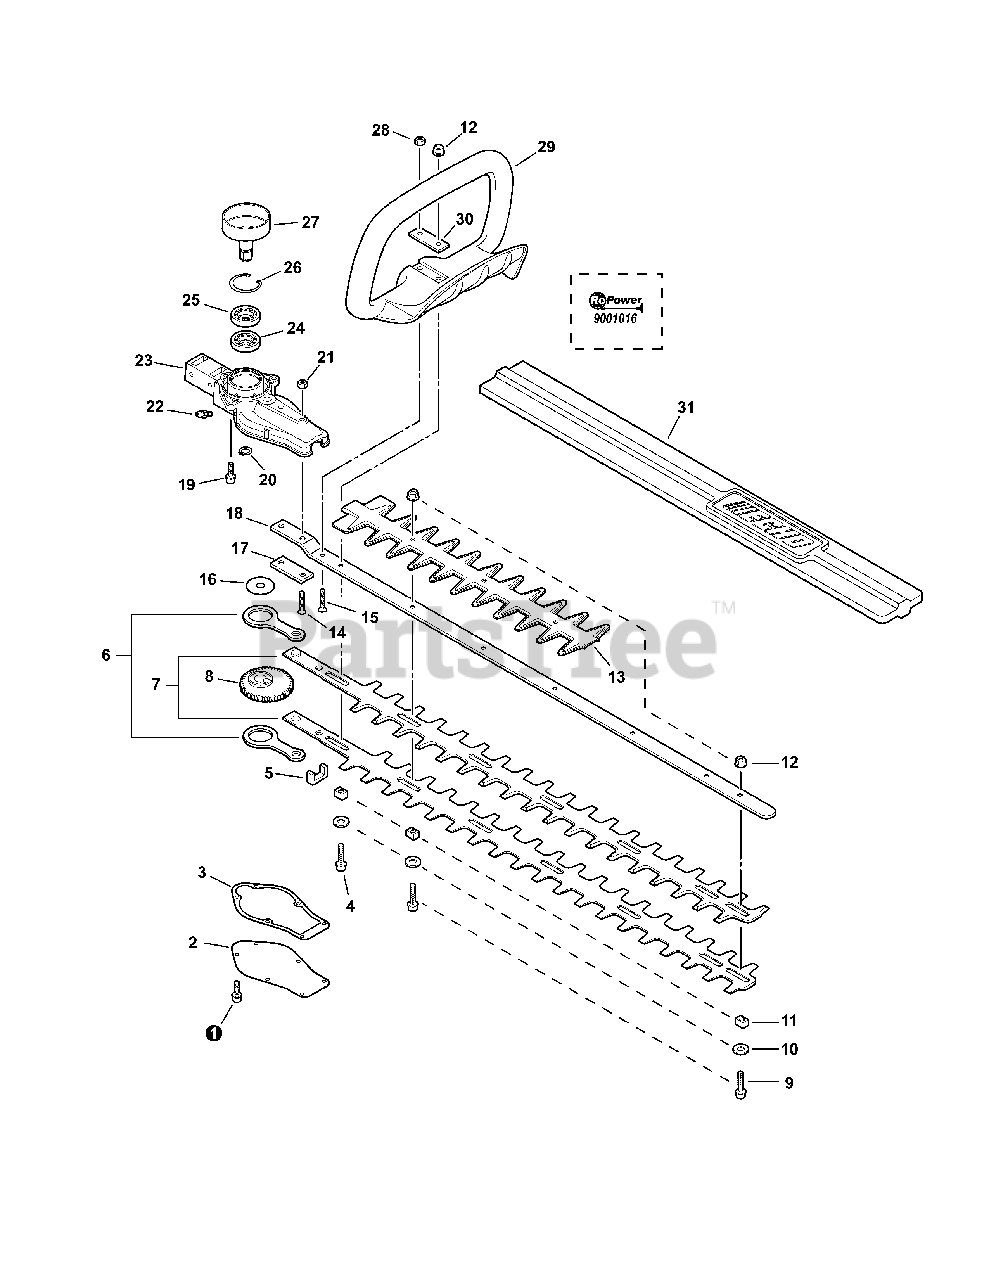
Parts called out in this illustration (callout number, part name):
1	SCREW - 4×10
2	LID, GEAR CASE
3	GASKET, GEAR CASE
4	SCREW - 5×40
5	SEAL, FELT
6	ROD, CONNECTING
7	BLADE, TRIMMER - 24"
8	GEAR - DRIVE
9	SCREW - 5×20
10	WASHER - 6
11	GUIDE, BLADE
12	LOCKNUT - 5
13	PROTECTOR, BLADE
14	SCREW - 6×25
15	SCREW - 5×30
18	SUPPORT, BLADE
19	SCREW - 5×20
20	RING, RETAINING - 14
21	LOCKNUT - 6
22	FITTING, GREASE
23	CASE, GEAR
24	BEARING, BALL - 6202
25	BEARING, BALL - 6202
26	RING, RETAINING - 35
27	DRUM, CLUTCH
28	LOCKNUT - 5
29	HANDLE - FRONT
31	COVER, BLADE - 24" (60cm)
32	RePower GEAR CASE/BLADES KIT
